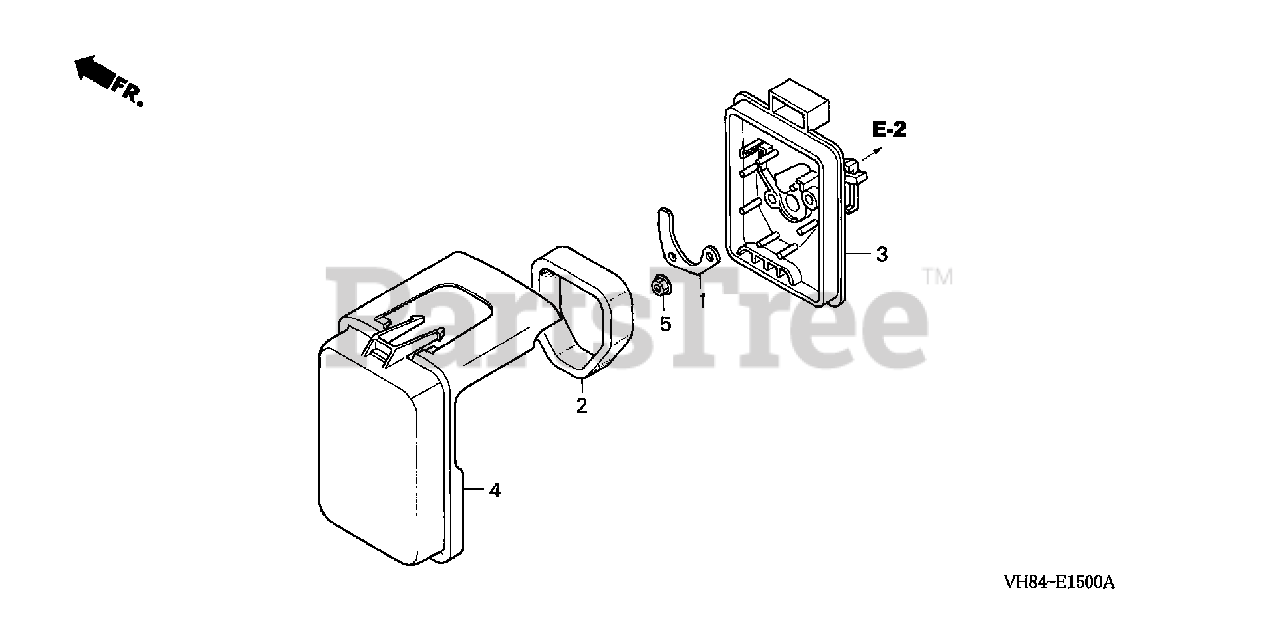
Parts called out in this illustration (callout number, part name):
1	PLATE, OIL TRAP
2	ELEMENT, AIR CLEANER
3	HOUSING, AIR CLEANER *NH1* (BLACK)
4	COVER, AIR CLEANER *NH1* (BLACK)
5	NUT, FLANGE (5MM)
